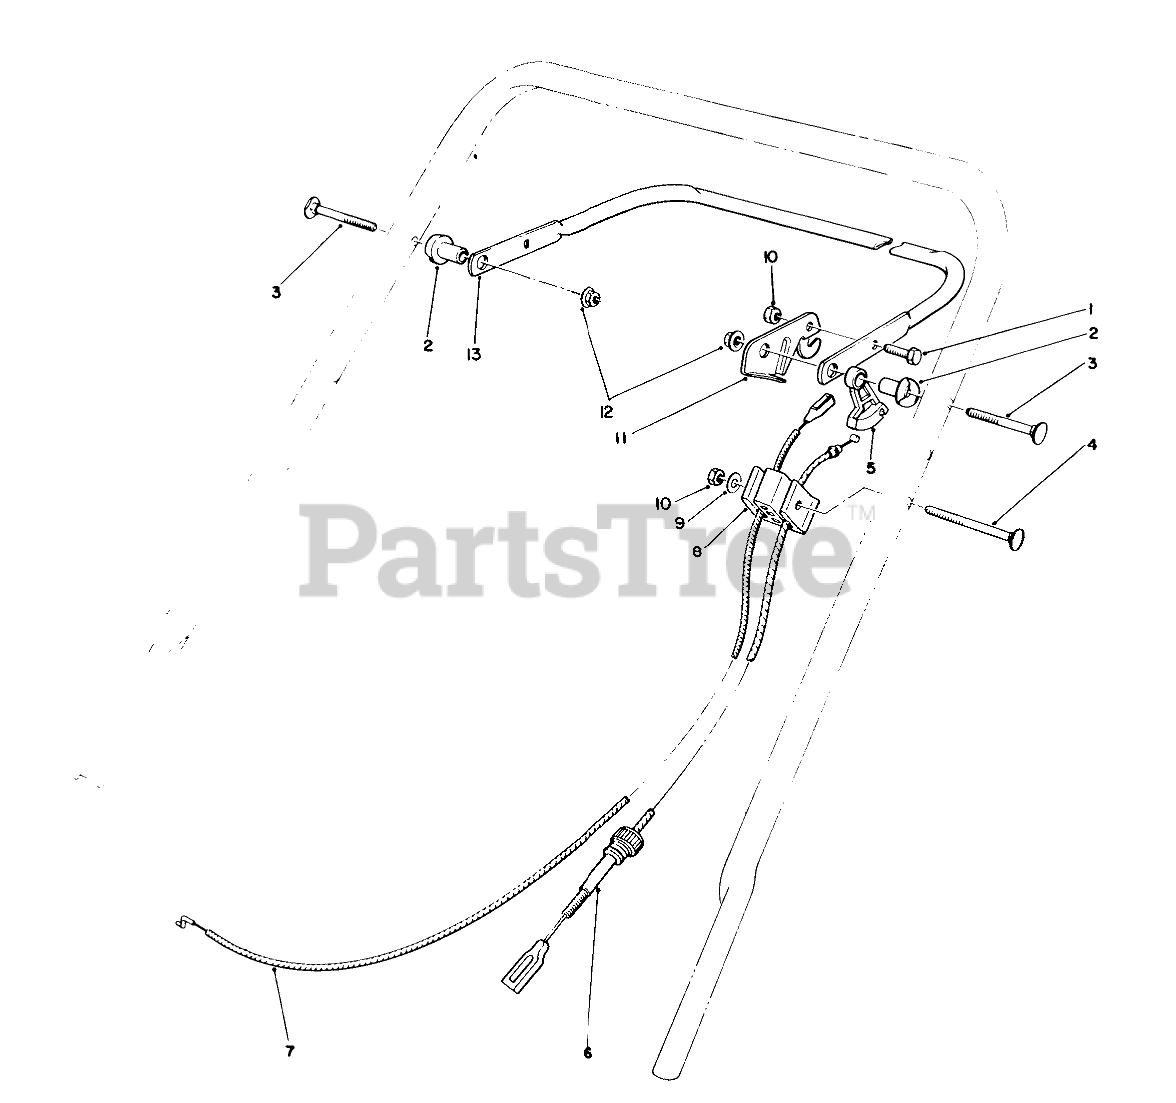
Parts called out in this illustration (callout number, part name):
1	SCREW-HH
2	SPACER-SUPPORT
3	5/16-18 X 2 HNDLE SCREW
4	HANDLE SCREW
5	LEVER-TRACTION
6	CABLE-TRACTION
7	BRAKE CONTROL
8	SUPPORT-CABLE
9	WASHER-FLAT
10	NUT-LOCK, NI
11	LEVER-CONTROL
12	NUT-LOCK, NI
13	Bar-Control
